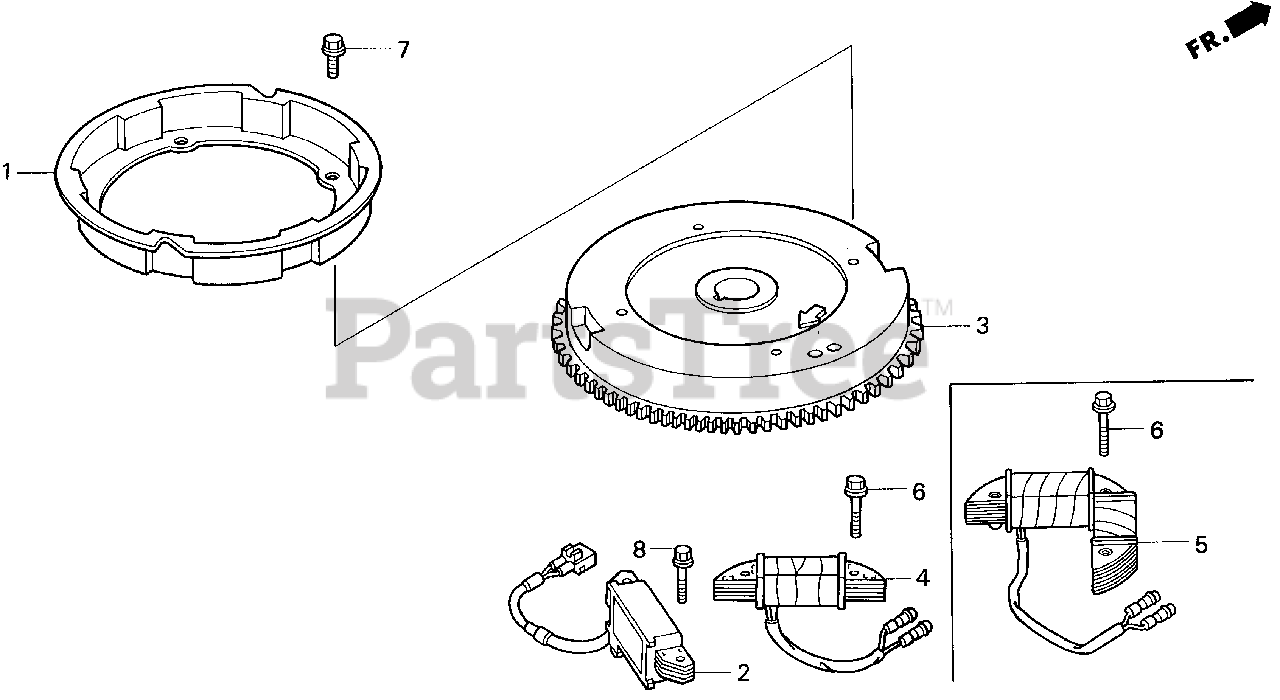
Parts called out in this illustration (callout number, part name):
1	PULLEY, STARTER
2	COIL ASSY., EXCITER
3	FLYWHEEL *TBLACK* (BLACK)
5	COIL ASSY., CHARGE (12V-10A)
6	BOLT, FLANGE (6X35)
7	BOLT, FLANGE (6X12)
8	BOLT, FLANGE (6X25)
